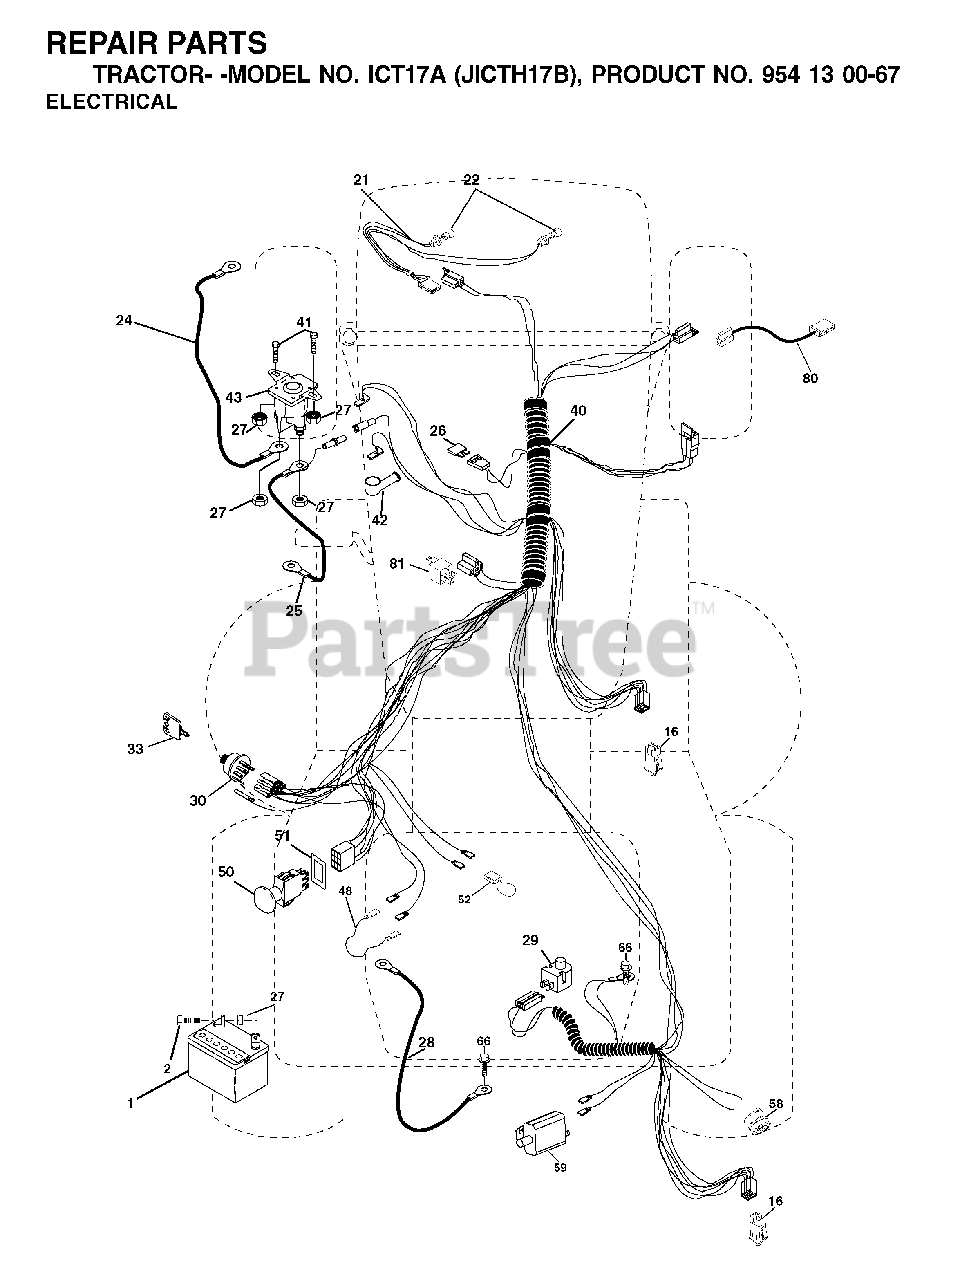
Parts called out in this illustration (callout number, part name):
1	REPL BY 532 12 38-99
16	SWITCH INTERLOOK PUSH-IN
21	HARNESS.W/LIGHT SOCKET
22	LIGHTBULB
24	BATTERY CABLE GT
25	CABLE BATTERY
26	FUSE 20AMP
27	NUT
28	CABLE GROUND
29	PLUNGER SWITCH (COLOR:OLIVE)
30	IGNITION SWITCH
33	KEY MLD GEN DELTA
42	TERMINAL COVER
43	SOLENOID
50	PTO SWITCH
51	RETAINING RING
52	WIRE PROTECTION LOOP
58	BUZZER
81	RELAY.ASSY.T
